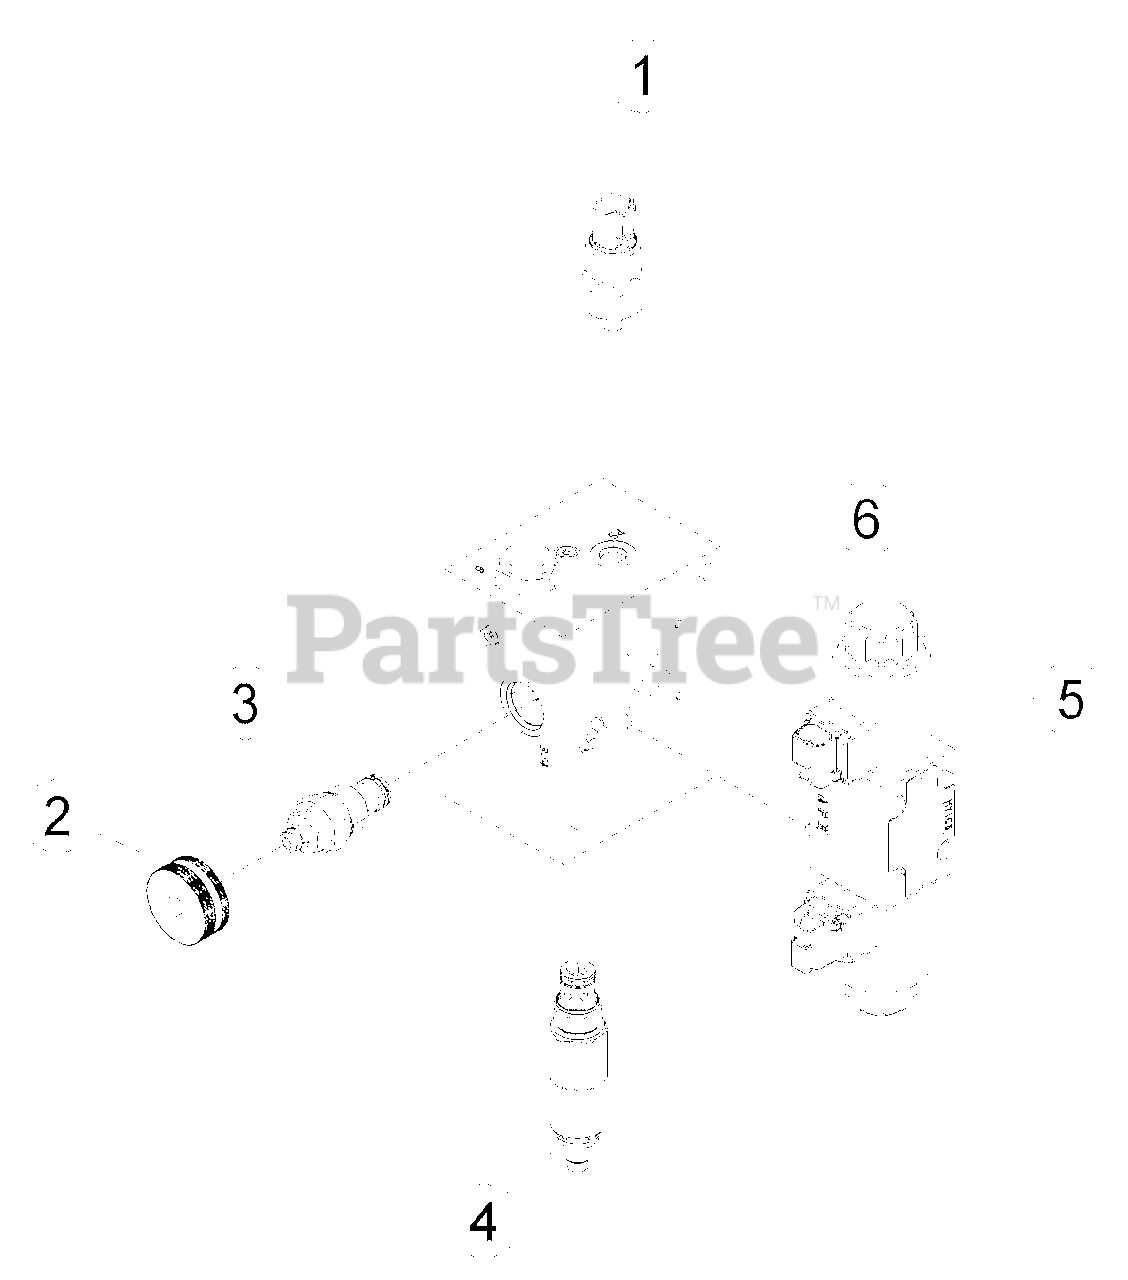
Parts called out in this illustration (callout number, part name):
1	SWITCH, PRESSURE GC
2	KIT, VALVE KNOB
3	VALVE, NEEDLE - 10 MOUNT
4	VALVE, DIFFERENTIAL SENSING
5	COIL, SOLENOID
6	NUT, COIL SOLENOID
